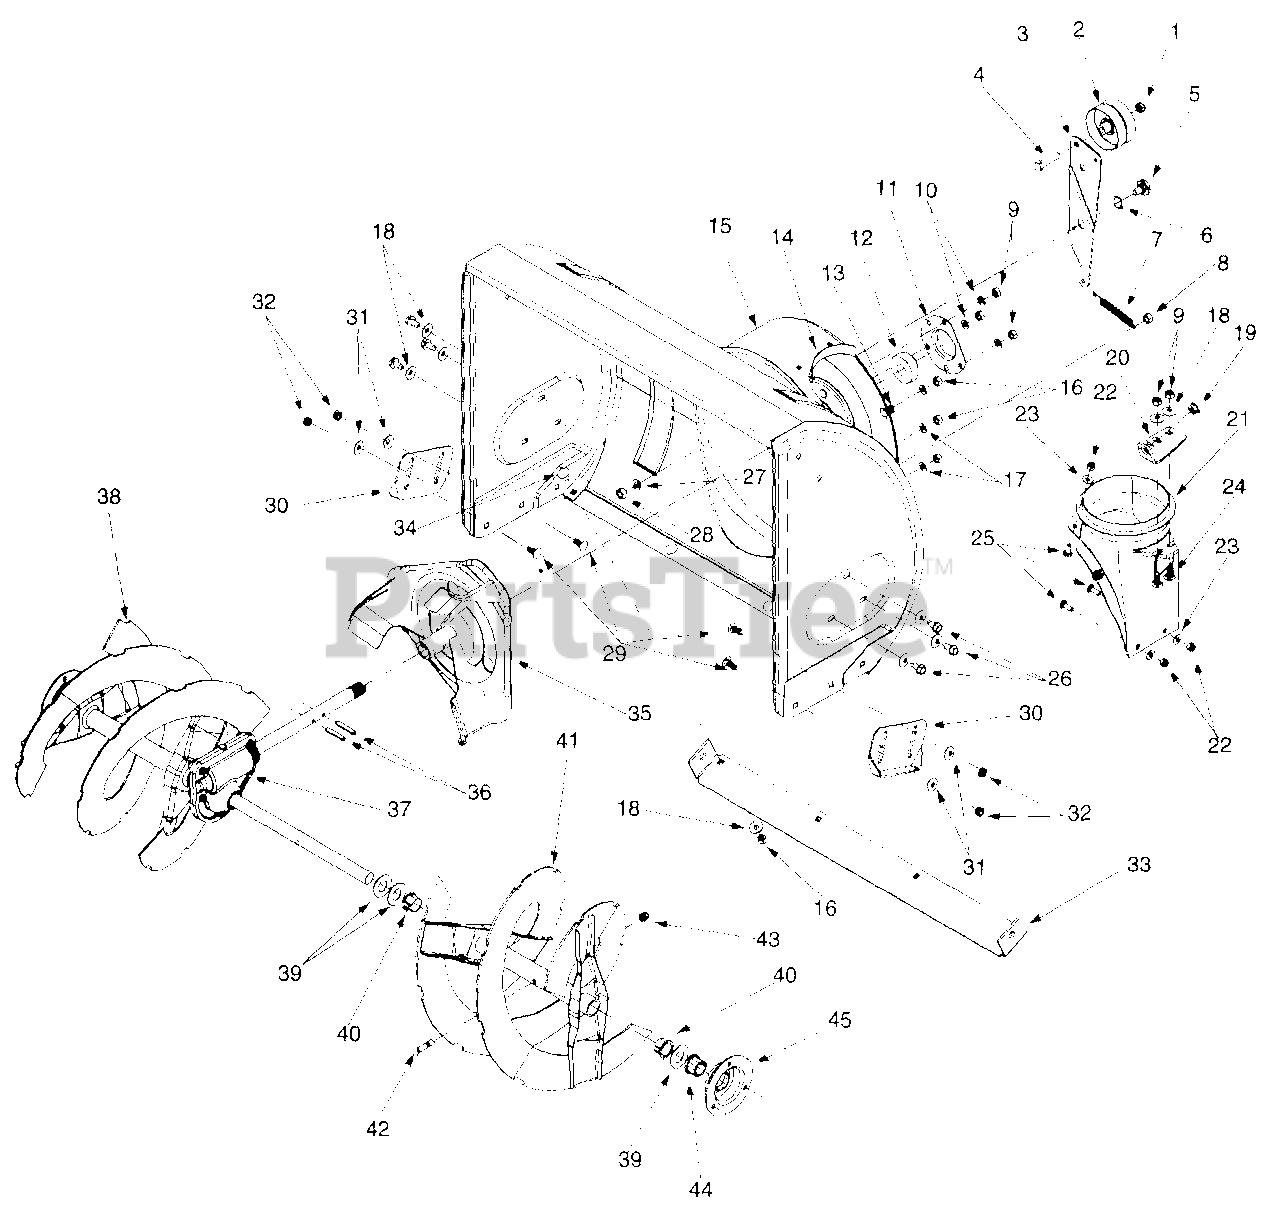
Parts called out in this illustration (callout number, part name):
1	Lock Jam Nut 3/8-24
2	Flat Idler
3	Auger Idler Arm
4	Hex Cap Screw 3/8-24 x 1.50
5	Shoulder Screw
6	Wave Washer
7	Extension Spring
8	Hex Nut 5/16-18
9	Hex Nut 5/16-18
10	Lock Washer 5/16
11	Housing
12	Ball Bearing
13	Carriage Bolt 5/16-18
17	Lock Washer 5/16
18	Bell Washer
19	Bushing
20	Chute Crank Bracket
21	Chute Adapter
22	Hex Lock Nut 1/4-20
23	Flat Washer
24	Carriage Bolt
25	Carriage Screw 1/4-20 x .75
26	Hex Washer Screw 5/16-18
27	Lock Washer 3/8
28	Hex Nut 3/8-16
29	Carriage Bolt 5/16-18 x .75
31	Bell Washer
32	Hex Nut 5/16-18
33	24" Shave Plate
33	26" Shave Plate
33	28" Shave Plate
34	Carriage Bolt 5/16-18 x .62
35	Impeller Assembly
36	Pin
37	24" Gear Assembly
38	Spiral 24" RH
39	Flat Washer
40	Flange Bushing
41	Spiral 24" LH
42	Shear Bolt 5/16-18 x 1.5
43	Lock Nut 5/16-18
44	Hex Flange Bearing
45	Bearing Housing
